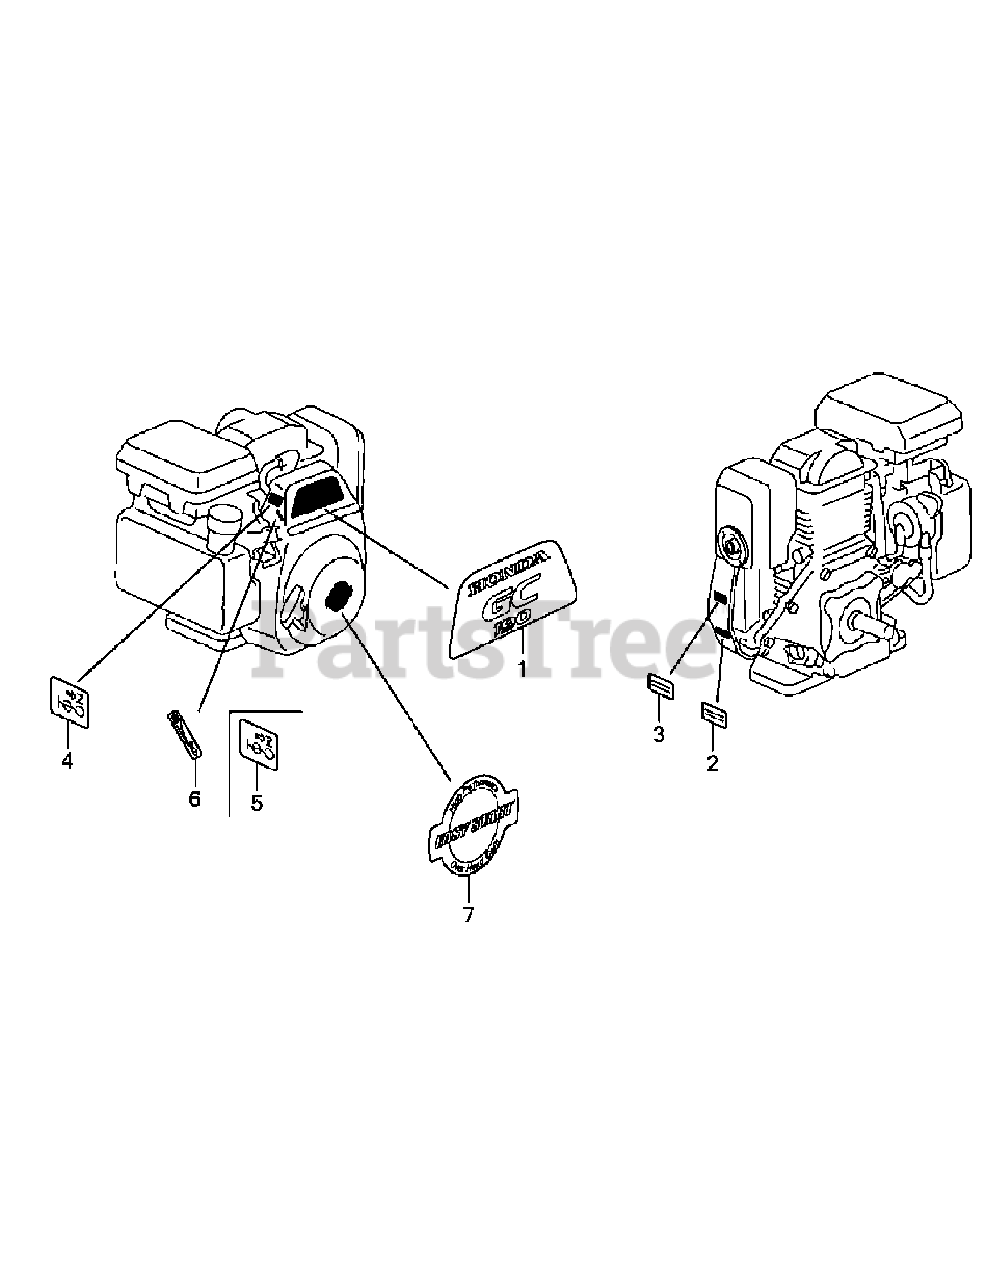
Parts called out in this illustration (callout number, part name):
1	Mark, Emblem (Gc190)
2	Label, Warning
4	Mark, Choke
6	Mark, Throttle Indication
